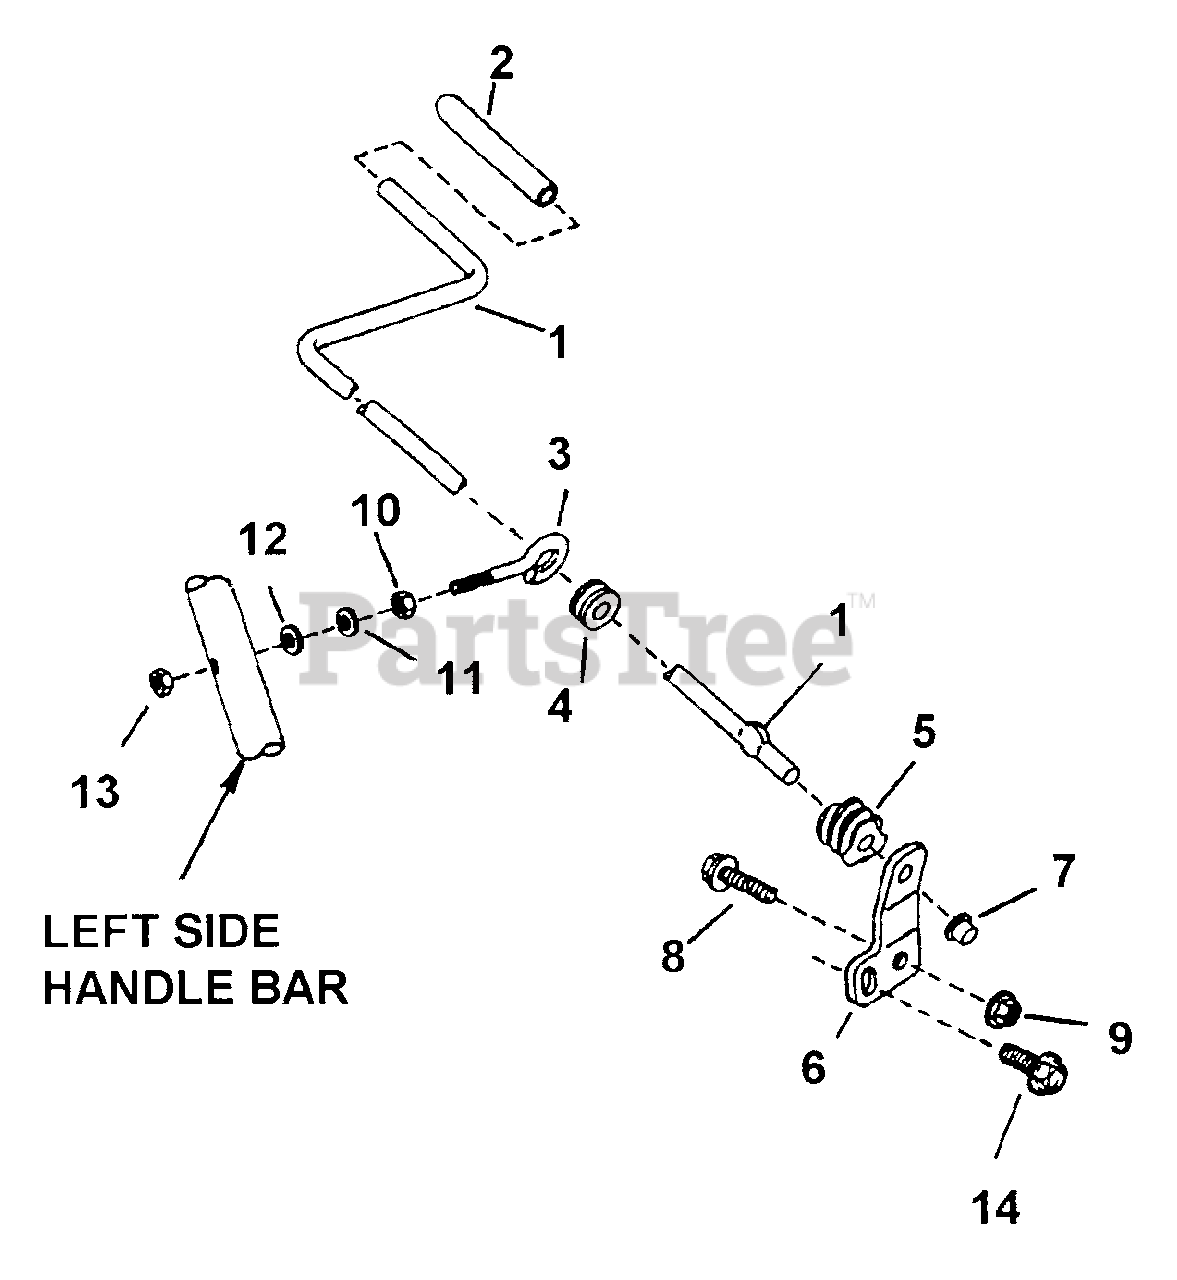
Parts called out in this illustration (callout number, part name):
1	CRANK, Chute
2	GRIP, Vinyl
3	BOLT, 5/16-18 Eye
4	GROMMET
5	WORM (Plastic)
6	BRACKET, Worm Shaft
7	NUT, 3/8" Push
8	SCREW, 5/16-18 x 5/8" Hex Head Cap, Grade 5
9	NUT, 5/16-18 Hex Flange Lock, Grade 5
10	NUT, 5/16-18 Hex, Grade B or 5
11	WASHER, 5/16 Internal Tooth Lock
12	WASHER, 5/16 Flat
13	NUT, 5/16-18 Hex Center Lock, Grade B
14	SCREW, #10-32 x 3/8" Hex Washer Self-Tap, (Torx)
